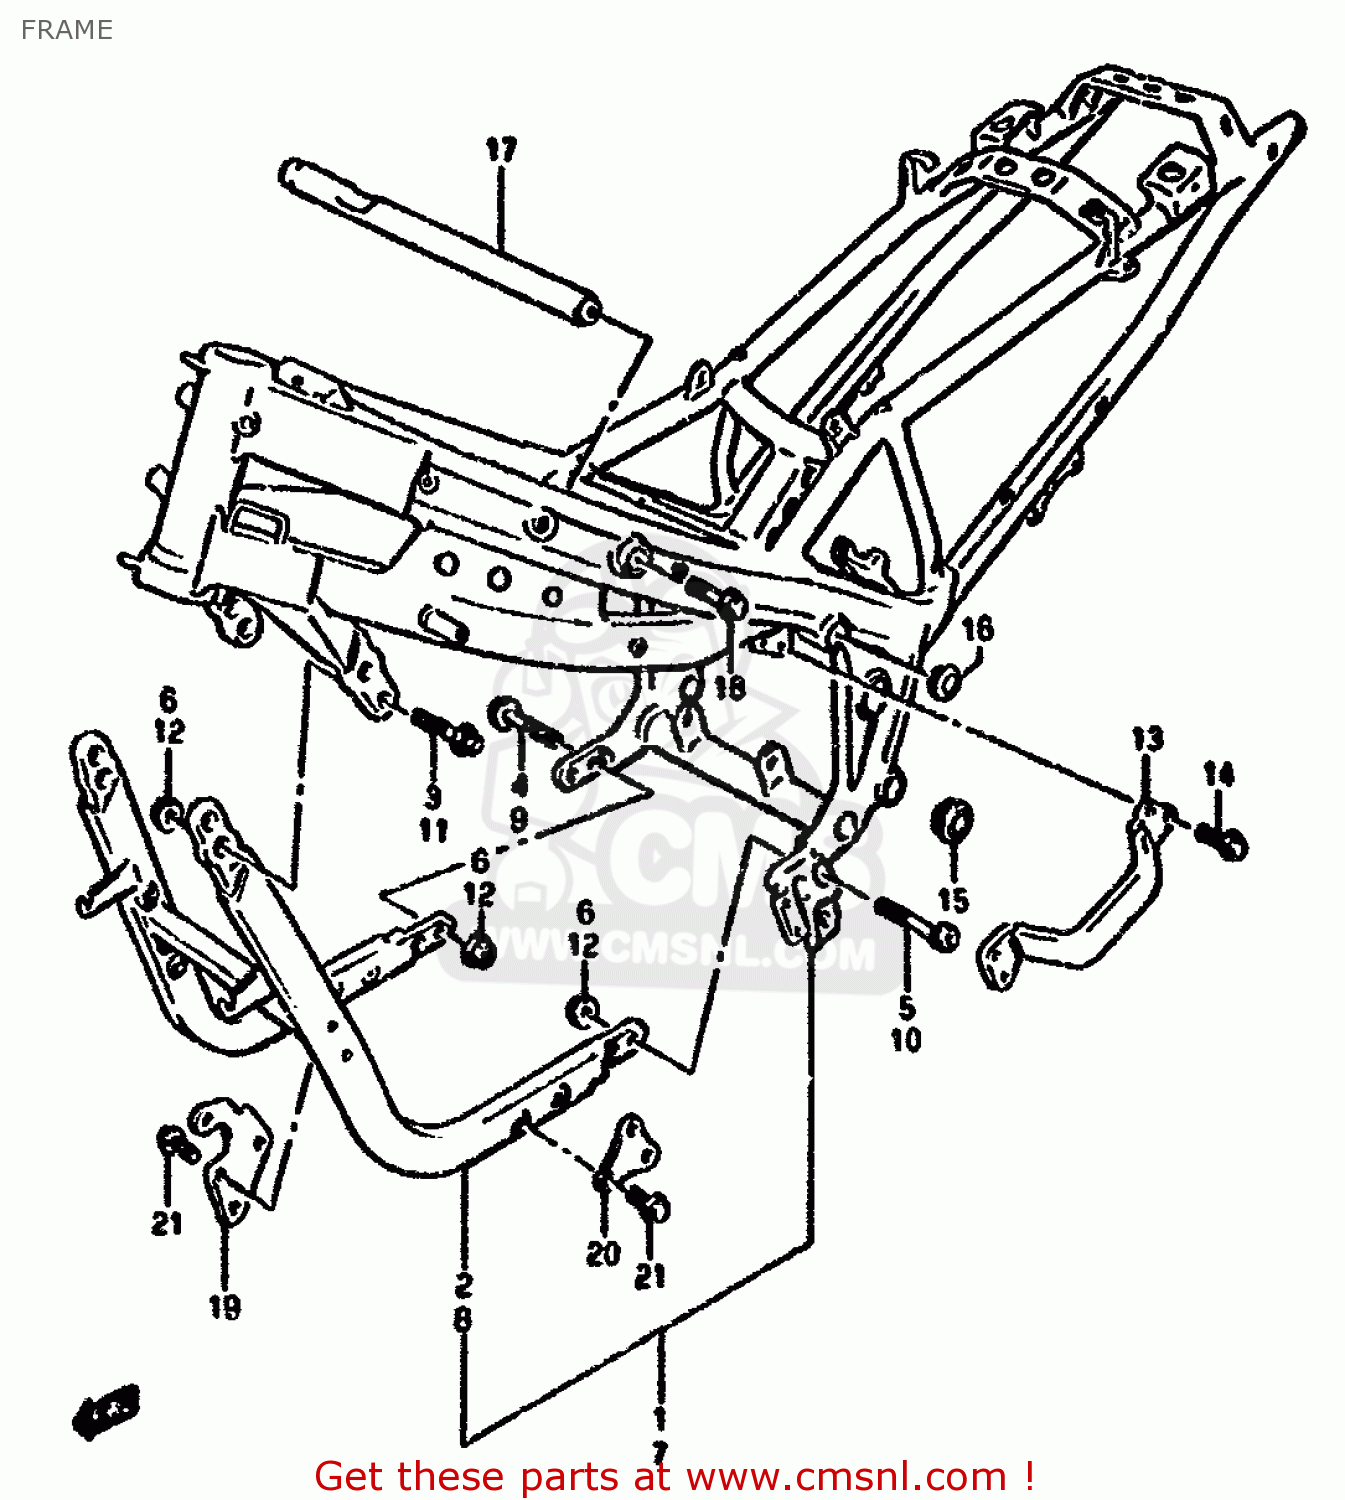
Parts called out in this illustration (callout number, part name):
1	FRAME
2	TUBE,FRAME
3	BOLT,FRONT
4	BOLT,REAR RH
5	BOLT,REAR LH
6	NUT
7	FRAME SET (SILVER)
8	TUBE,FRAME,DOWN
9	BOLT
10	BOLT
11	BOLT
12	NUT
13	TUBE,FRAME REINFORCE RH
14	BOLT
15	CAP,FRAME NO.1
16	CAP,FRAME NO.2
17	BRIDGE,TANK RAIL
18	BOLT,TANK BRIDGE
19	PLATE,ENGINE MOUNTING
20	PLATE,ENG MTG NO.2
21	BOLT
